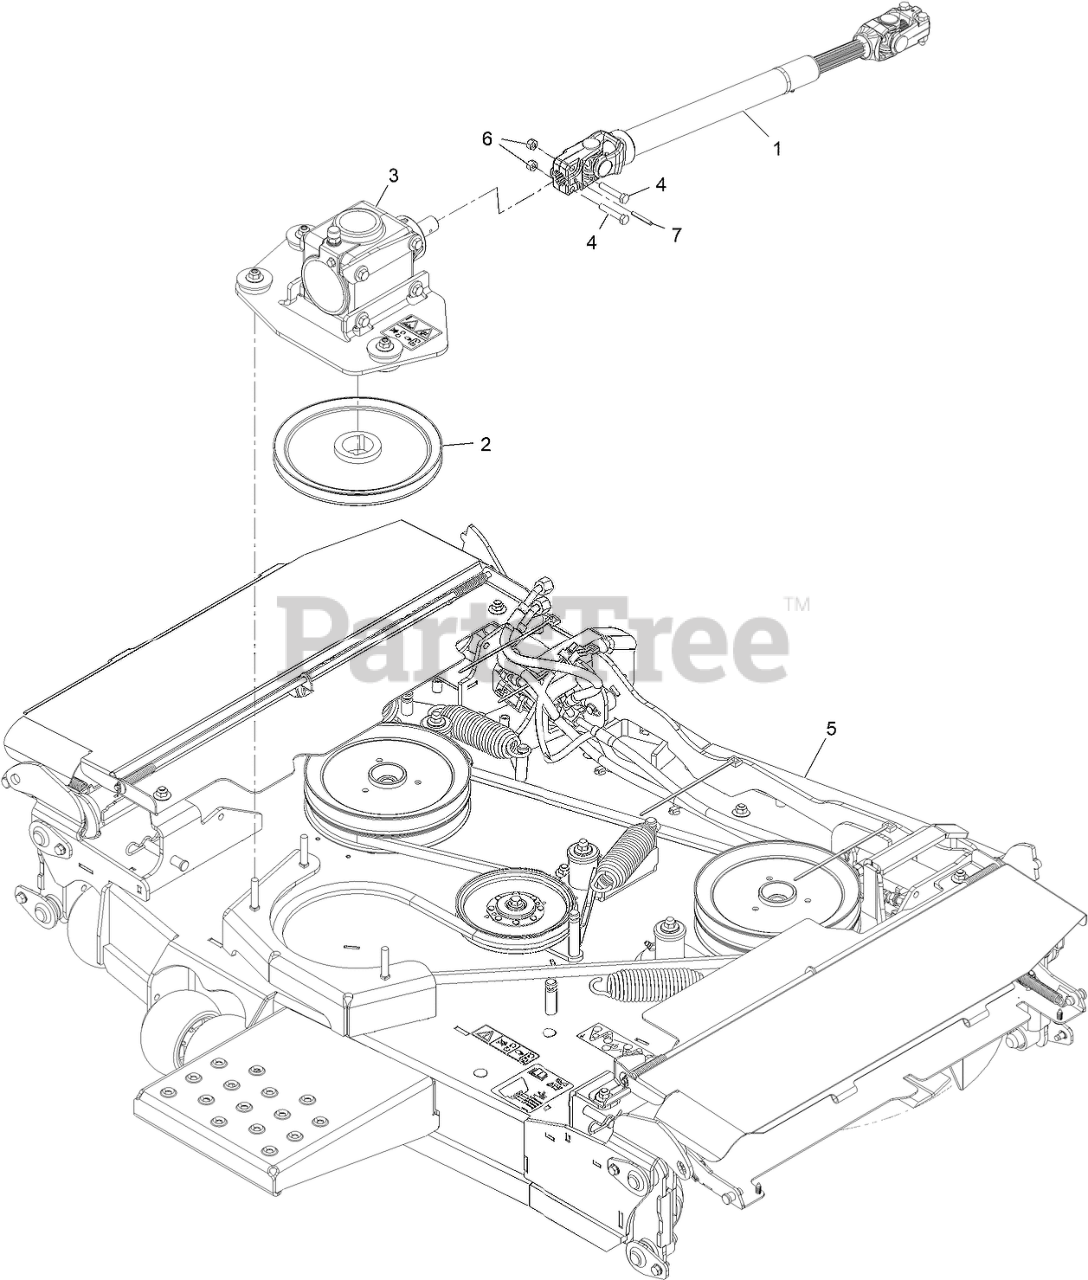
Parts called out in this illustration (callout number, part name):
1	DRIVESHAFT ASM
3	Gearbox ASM
4	SCREW-HH
6	NUT-LOCK, NI
7	PIN-ROLL
